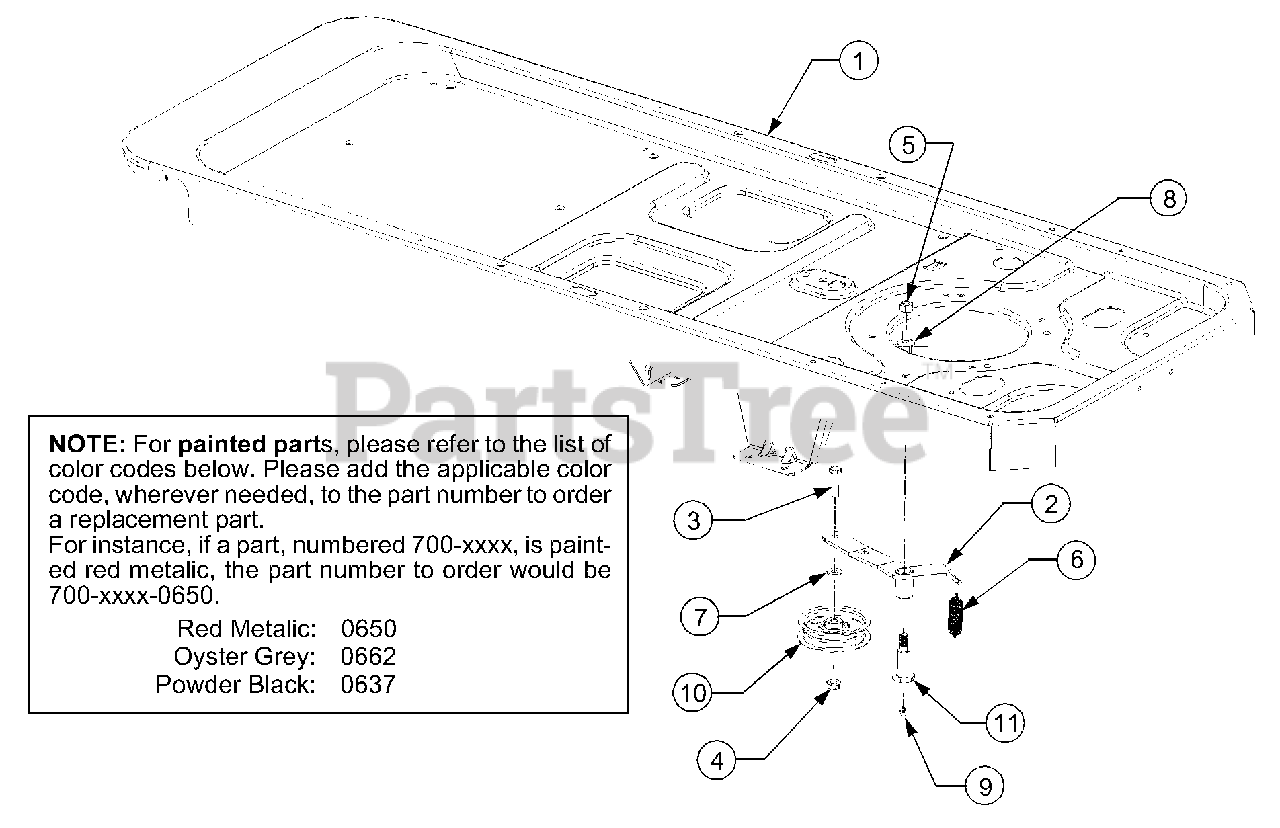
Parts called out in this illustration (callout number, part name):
4	Nut, Hex Flange Lock, 3/-16 GRF
5	Nut, Hex Lock, 7/16-14 GRA
6	Spring, Extension, .75 x 5.06
7	Washer, Flat, .406 x .875 x .059
8	Washer, Flat, .45 x 1.25 x .164 HT
9	Fitting, Lube, 3/16 Drive
10	Screw, Shoulder, .68 x 1.59
11	Pulley, Idler, 3.50 Dia.
